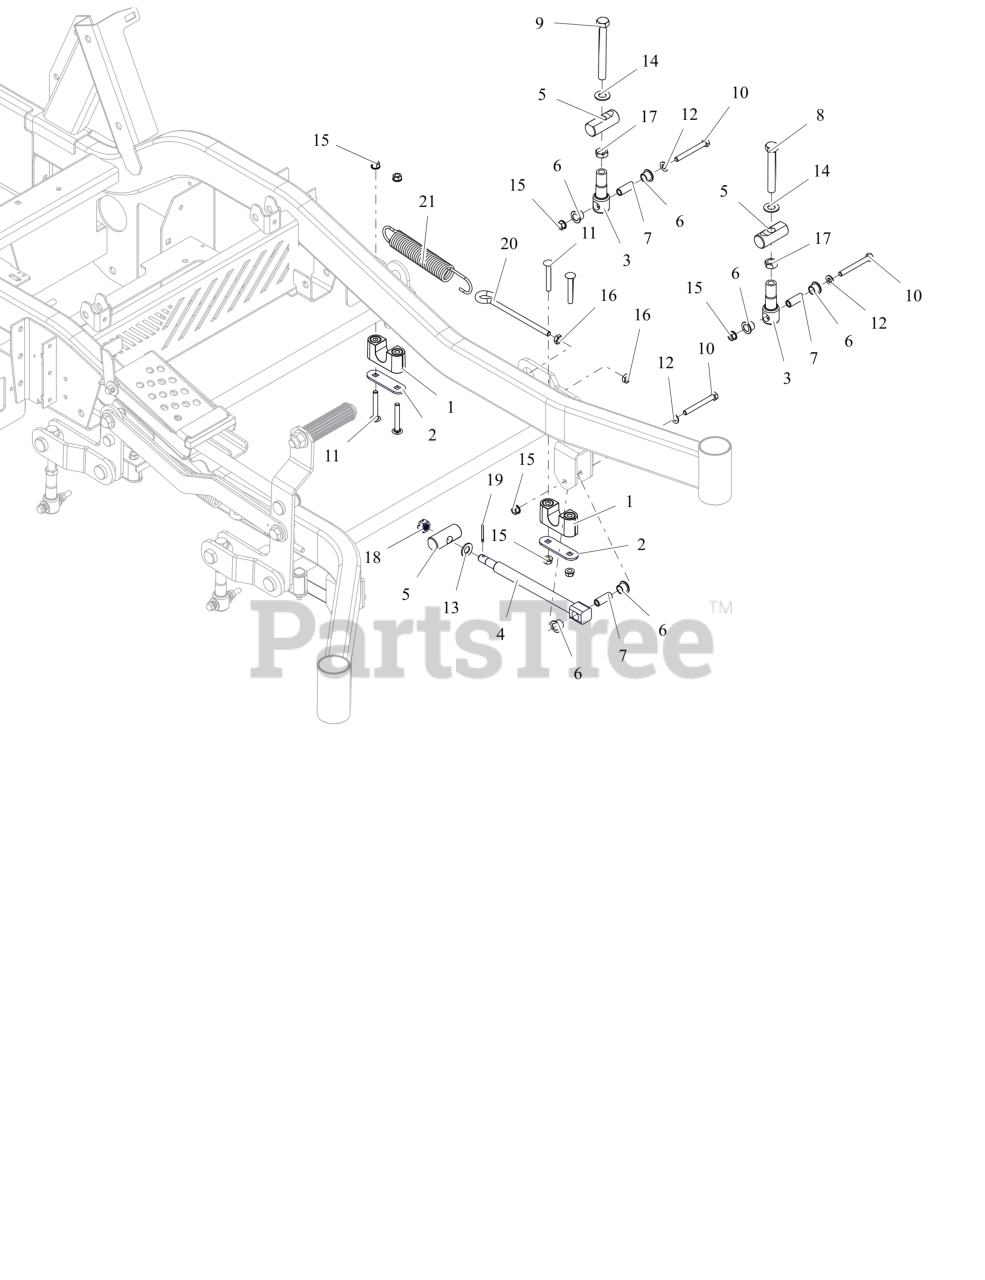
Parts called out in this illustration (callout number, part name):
1	ASM-BUSHING, DECK LIFT
2	PLATE, BEARING SUPPORT
3	LINK, DECK LIFT FORMED
4	DRAG,LINK-HD
5	PIN, DECK LIFT
6	BSHG, FLANGED .50X.625X.50X.062
7	SPCR, .31X.50X1.265
8	BLT, HEX 0.5-13X3.5F GR5 ZCC
9	BLT, HEX .50-13X4.50F G8 ZCC
10	BLT, HEX .31-18X2.75 G5 ZCC
11	BLT, RHSSN.31-18X2.25 G5 ZCC
12	WSHR,FLT .344X.688X.065 ZCC
13	WSHR, BLVL .505 X 1.000 X .073 ZCC
14	WSHR, FLT .557X1.040X.102 ZCC
15	NUT,LK-CTR-FLG .31-18 GF ZCC
16	NUT-JAM .375-16 G2 ZCC
17	NUT-JAM .500-13 G2 ZCC
18	NUT-SL .50-13
19	PIN,CTR.12X1.25EXTPRSQCT ZC120
20	BOLT,.38-16 X 5.25-.62 DIA EYE
21	SG-TENS .162X1.25X8.25 WLD 25
